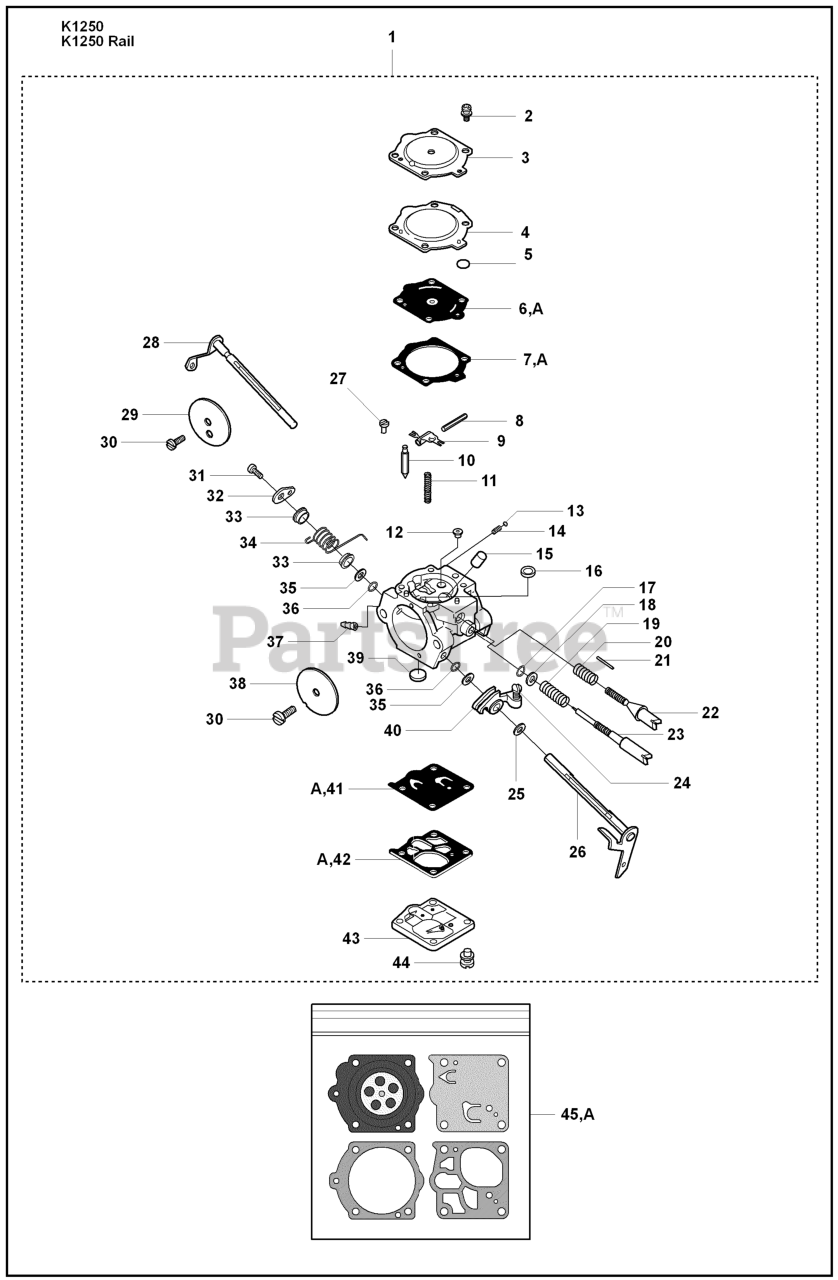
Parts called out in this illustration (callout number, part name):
1	CARBURETOR WGA WALBRO
3	COVER DIAPH
6	METERING DIAPHRAGM GSKT
10	INLET NEEDLE
11	LEVER SPRING
16	WELCH PLUG
19	PRESSURE SPRING
20	SPRING-MIX NEEDLE
21	ADJ NEEDLE-LO,CARB
22	ADJ SCREW-LO,CARB
23	HI-NEEDLE,CARB
26	THROTTLE SHAFT
29	CHOKE SHUTTER
30	SCREW SHUTTERS
31	SCREW
34	SPRING,THROTTLE RETURN
37	FUEL NIPPLE-CARB
38	SHUTTER-THROTTLE
39	FUEL INLET SCREEN
41	DIAPHRAGM/PUMP
42	GASKET
44	SCREW W/ WASHER
45	DIAPHRAM SET
